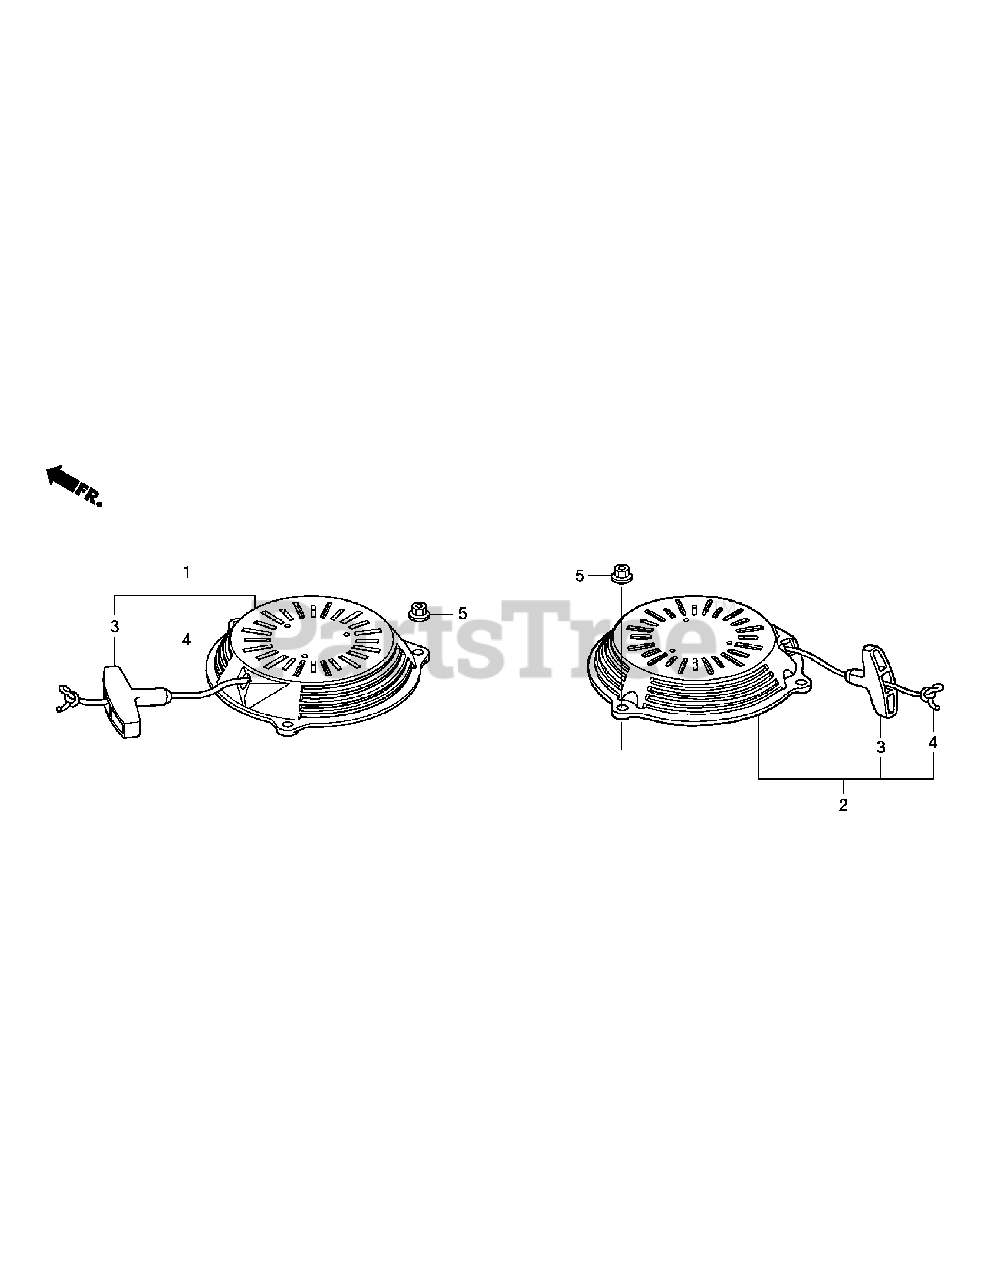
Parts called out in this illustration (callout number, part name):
1	STARTER ASSY., RECOIL
2	STARTER ASSY., RECOIL
3	GRIP, STARTER
4	ROPE, RECOIL STARTER
5	NUT, FLANGE, 6MM
